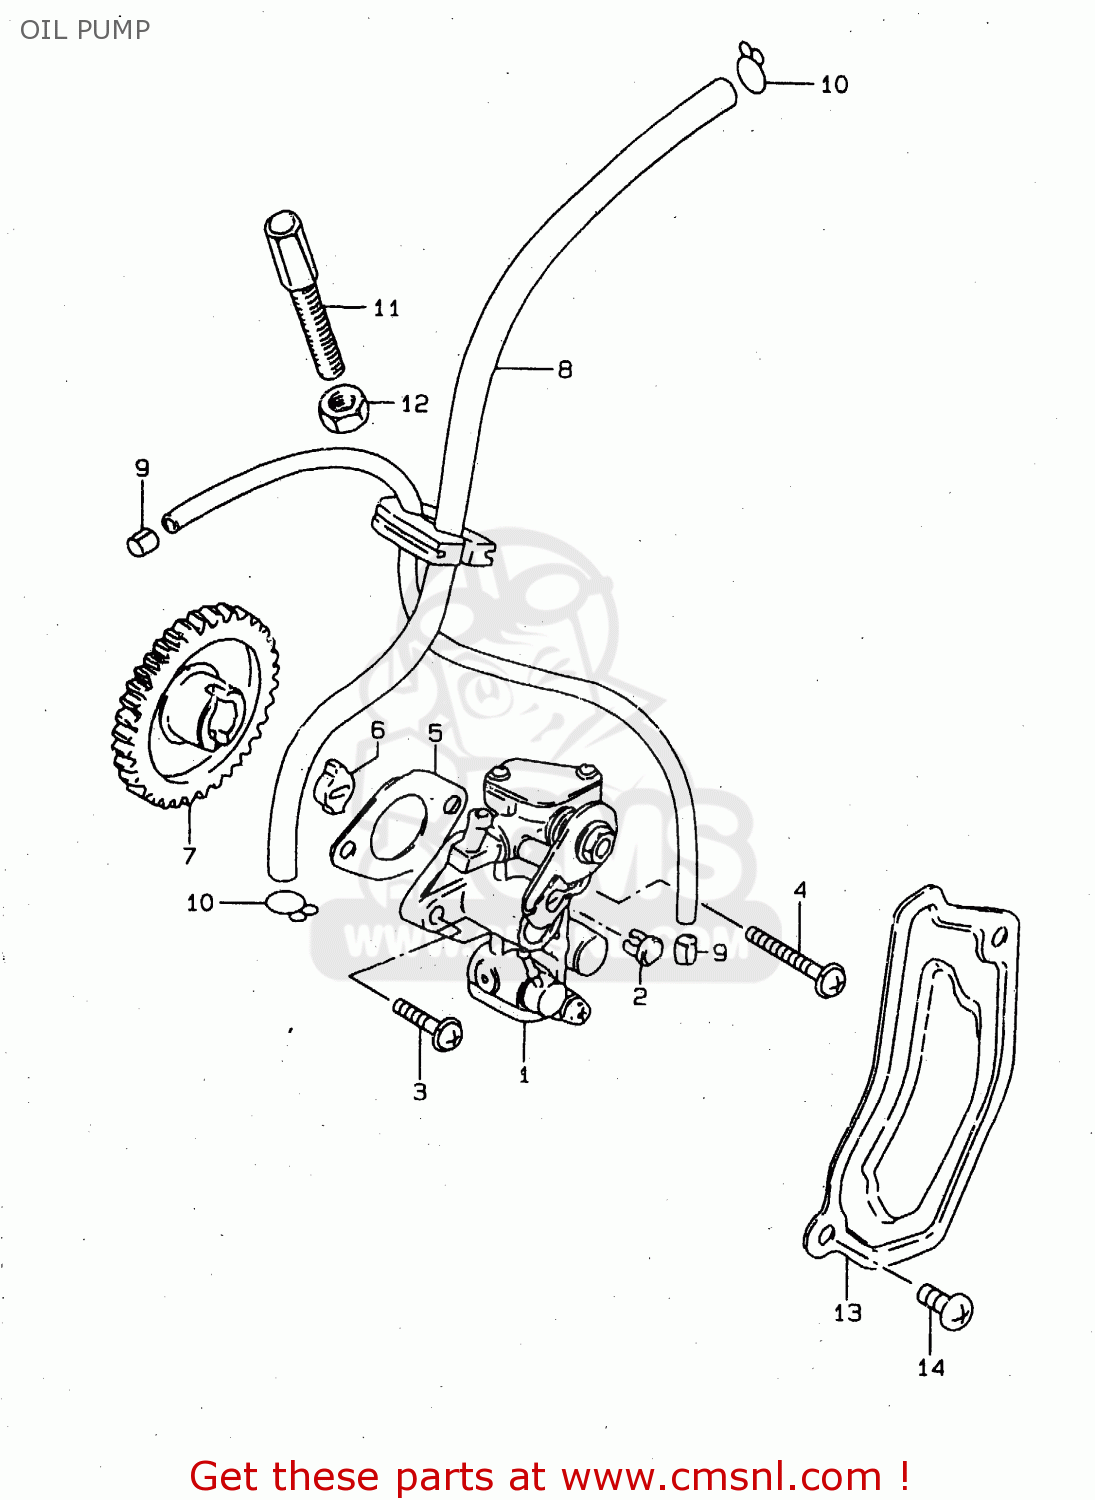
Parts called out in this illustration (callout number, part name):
1	PUMP ASSY,OIL
2	TERMINAL,CABLE
3	SCREW
4	SCREW
5	GASKET,OIL PUMP (NAS)
6	PIECE,OIL PUMP DRIVE
7	GEAR,OIL PUMP DRIVE
8	HOSE,OIL NO.2
9	CLIP
10	CLIP
11	BOLT
12	NUT
13	CAP,OIL PUMP INSPECTION
14	SCREW
